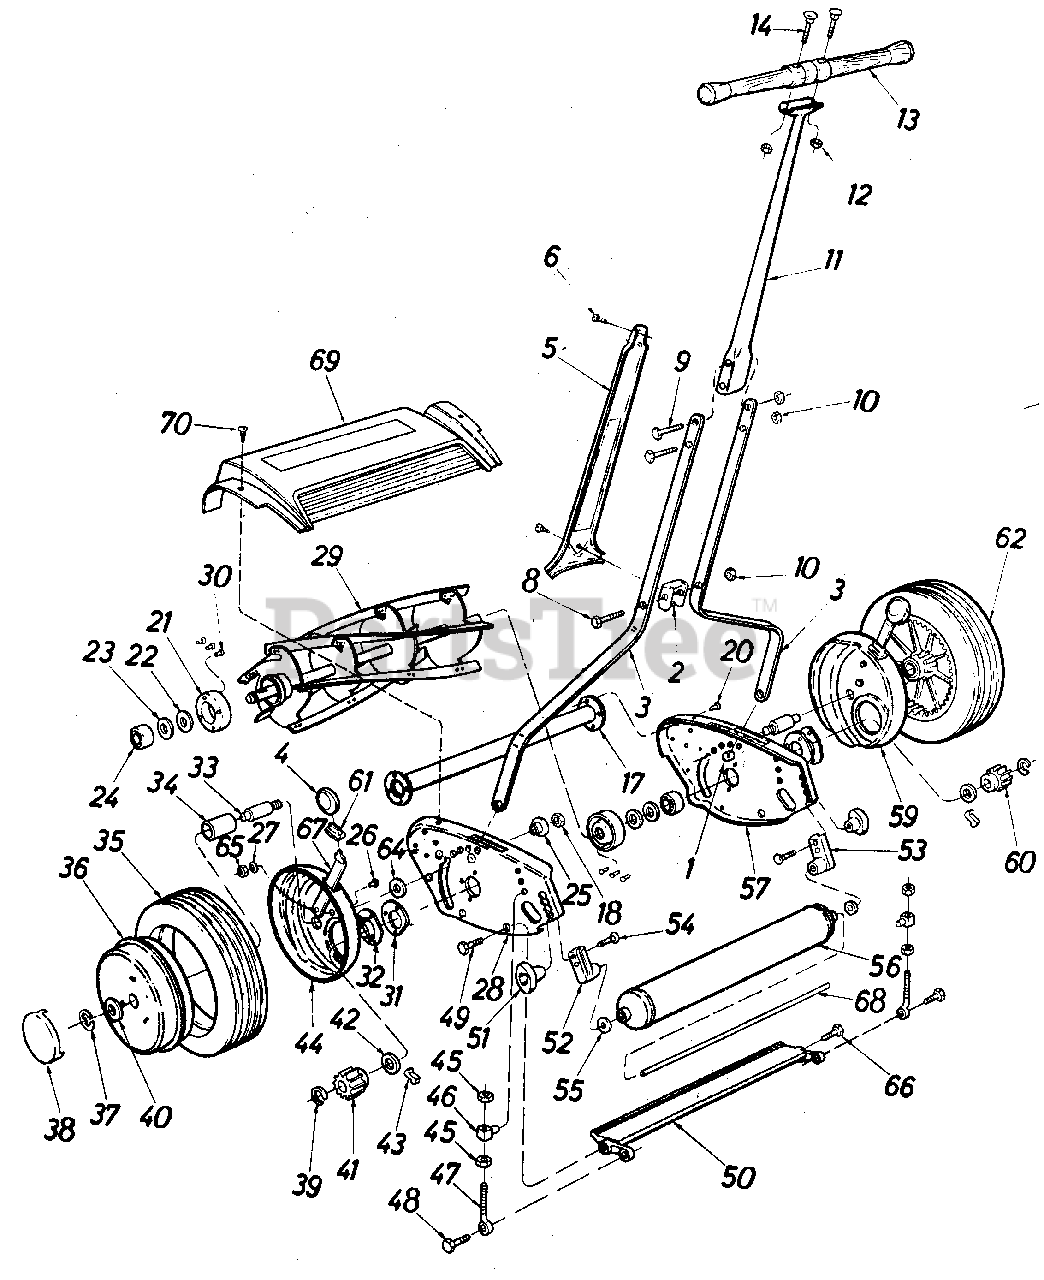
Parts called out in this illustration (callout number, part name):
1	Trunnion
2	Spacer
3	Handle Brace 16"
4	Knob Wheel Adjust.
5	Handle Panel
6	Ph. Hd. Scr. #10 x .38 Lg.
8	Hex Scr. 5/16-18 x 2.50 Lg.
9	Hex Scr. 5/16-18 x 2.25 Lg.
10	Hex Nut 5/16-18 Thd.
11	Handle Shaft
12	Hex Nut 1/4-20 Thd.
13	Cross Handle
14	Carriage Bolt 1/4-20 x 1.75" Lg .
17	Spacer Tube Ass'y.
18	Hex L-Nut 5/16-24 Thd.
20	Rivet 3/16 Dia. x 3/8" Lg.
21	Retainer
22	Felt Washer
23	Felt Retainer
24	Bearing
25	Bushing
26	Hex Scr. #10-32 x 3/8" Lg.
27	Washer
28	End Plate Ass'y. L.H.
29	18" Reel Ass'y.
30	Rivet 3/16 Dia. x 13/32 " Lg.
31	Retainer
32	Pinion Housing
34	Bearing
36	Wheel Ass'y.
37	Retaining Ring
38	Hub Cap
39	Retaining Ring
40	Fl-Wash. .38 I.D. x 1.25" 0. D.
41	Pinion Gear L.H.
42	Felt Washer
44	Gear Housing Ass'y. L.H.
45	Hex Nut 3/8-24 Thd.
46	Trunnion
47	Screw Cutter Bar Adj.
48	Screw Rear
49	Screw Pivot
50	Cutter Bar
51	Roller Adj. Knob
52	Roller Brkt. L.H.
53	Roller Brkt. R.H.
54	Roller Adj. Bolt
55	Fl-Wash. .312" I.D. x .75" O.D.
56	18" Roller
57	End Plate Ass'y. R.H.
59	Gear Housing Ass'y. R.H.
60	Pinion Gear R.H.
61	Dust Cover
62	Wheel Ass'y. Comp. 9 x 1.75
64	Washer
65	Hex Nut #10-32 Thd.
66	Screw Cutter Bar
67	Spring and Trunnion Ass'y.
68	Roller Shaft
69	Plastic Cover
70	Self Tapping Scr. #10 x 1/2" Lg.
